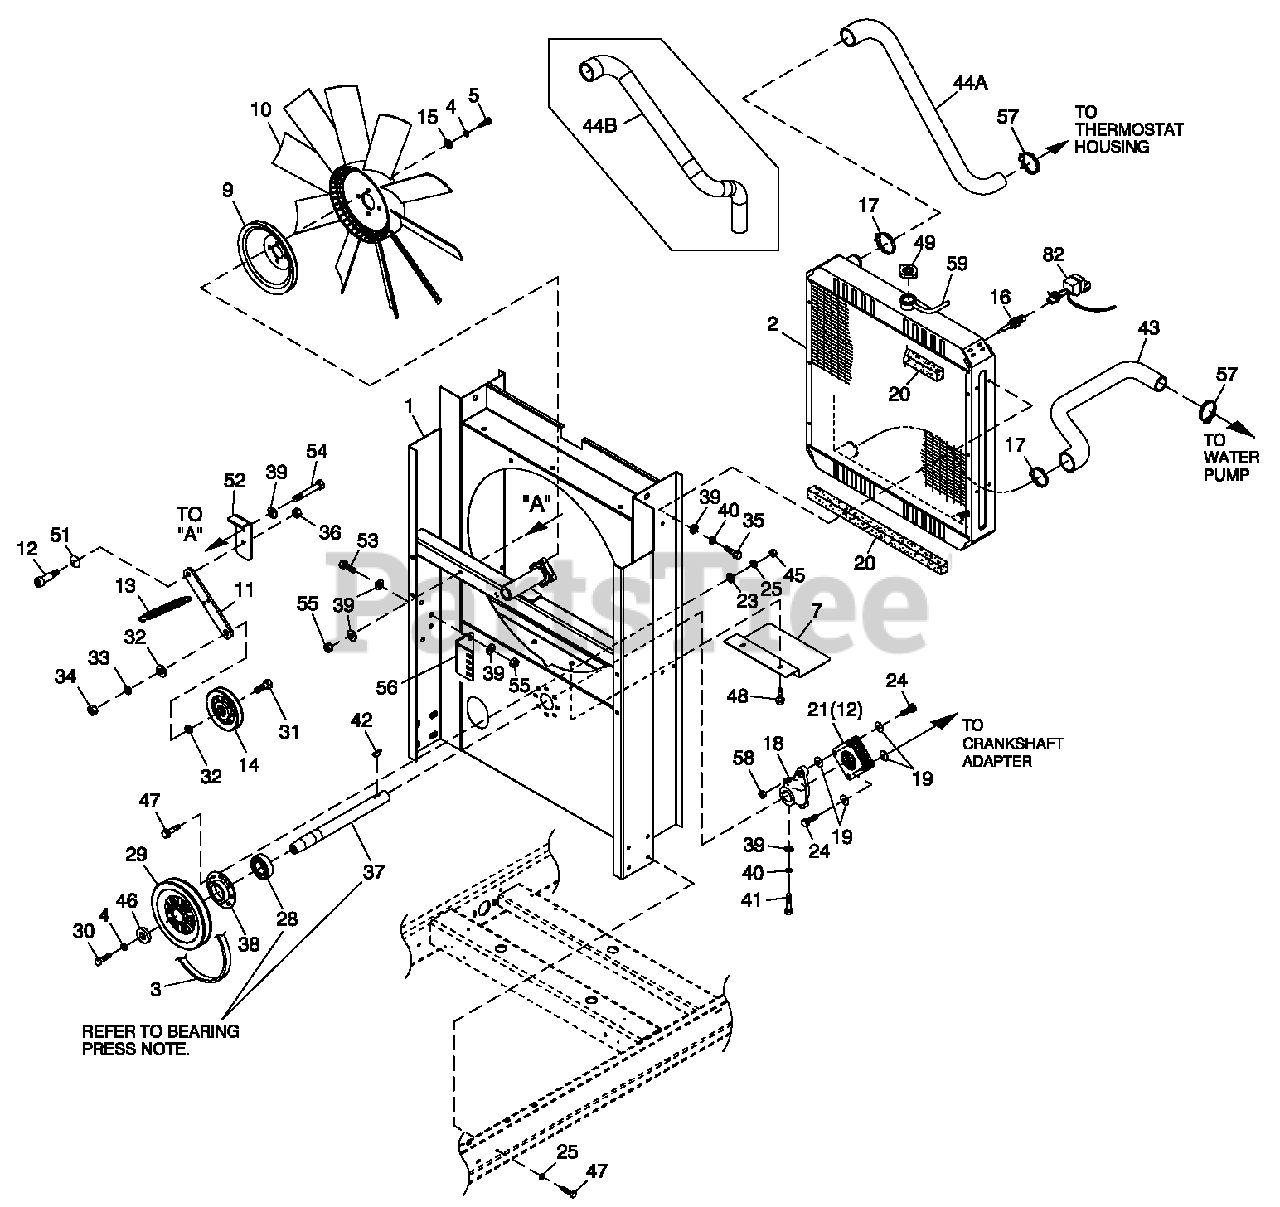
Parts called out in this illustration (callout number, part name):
1	WELDMENT RADIATORSUPPORTC2
2	RADIATOR 598 X 568 X 49 CPL RH
3	V-BELT 31/64" X 57-3/8"
4	WASHER LOCKM10
5	SCREWHHC M10-1.5X30 G10.9
7	SHIELD RADIATOR C4
9	PULLEY FANV-GROOVE9"
10	FAN COOL 22" D IA 10 BLADE LH
11	FLATTENSIONERARM
12	SHOULDER BOLT 3 /8X 1/2"
13	SPRING TENSION CPL
14	PULLEY V-BELT 4" FLANGED
15	WASHER FLAT 3/8-M10 ZINC
16	PROBE COOLANT LEVEL 3/8NPTF
17	CLAMP HOSE#28 1.32-2.25
18	HUB FLEX PLATE
19	WASHERFLEX (THIN)
20	TAPE FOAM 1X 1(26.75' LG)
21	DISKFLEX
23	WASHERFLAT 1/4-M6 ZINC
24	SCREW HHC 5/16-24X1.124
25	WASHERLOCK M6-1/4
28	BEARING #6205 2NSE C3 E SRI2 S
29	PULLEY 5.125" DIA MACHINED
30	SCREW HHC M10-1.5X30 G88
31	SCREW HHC 1/2-13X 2" G8
32	WASHERFLAT 1/2ZINC
33	WASHER LOCK 1/2
34	NUT HEX 1/2-13 STEEL
35	SCREW HHFCM8-125 X 2 0W M 6
36	NUT HEX LOCK 5/16-18 NY INS SS
37	SHAFT FAN DRVE
38	RETAINER BEARING
39	WASHERFLAT 5/16-M8ZINC
40	WASHER LOCKM8-5/16
41	SCREW HHC M8-1.25X 45 C8.8
42	KEY WOODRUFF 4X 19D
43	HOSE LOWER RADIATOR G2
44A	HOSE UPPER RADIATOR G2
44B	HOSE UPPER RADIATOR G2
45	NUT HEX M6X 1.0 G8YELCHR
46	SPACER .5X 1.5 X .2 5 STL/ZINC
47	SCREW HHFCM6-10 X 2 0 G8.8
48	SCREW THF M6-1 X 16 N WAZ/JS
49	CAP RADIATOR 13 PS I
51	WASHER BELLEVILLE .75X.38X.028
52	TENS ION ER ARM SUPPORT BENT 90
53	SCREW HHC M8-1.25 X 20 C8.8
54	SCREW HHC M8-1.25 X 75 C8.8
55	NUT HEX LOCK M8-1.25 NY INS
56	BRACKET TENSIONERSPRING
57	CLAMP HOSE #24 B1.06-2.00
58	NUT HEX LOCK 5/16-24 NY INS
59	HOSE 9/32 ID(36' LG)
60	CAC504WX152H X 5 0D 2 .4 L G2
61	CLAMP CNSTTENSON 1.75-2.625
62	HOSE 2"IDX 3.0"LG
63	TUBECAC N G2 TURBO
64	TUBECAC OUT G2 TURBO
65	SCREW THF M6-1 X 30 N WA DELTA
66	OIL LINE REMOTE ENG/COOLER
67	ADAPTOR 1/2 NPT X 37JIC 3/4-16
68	COOLER OIL 2 4 L G2 TURBO
69	ADAPTE R90D J IC 3 7 1 /2NPT X 3/4
70	TANK COOLANT RECOVERY
71	BRACKET COOLANT TANK
72	MOUNT OIL COOLER 2 .4 LG 2
73	ADAPTE R45D J IC 3 7 1 /2NPT X 3/4
74	MOUNT REMOTE OIL FILTER2.4G2
75	NIPPLE-OL FILTER
76	FILTER1.5L/24LG2 OIL
77	SCREW HHC M8-1.25 X 25 C8.8
78	BRACKET RESERVOIR MOUNTING
79	HOSE 2"IDX 3.0"LG
80	CLAMP STLVNL.75 X .343 Z
82	ASSYPCB LCLSENSOR (USEWITH I/N16, P/N QH18270NLY)
